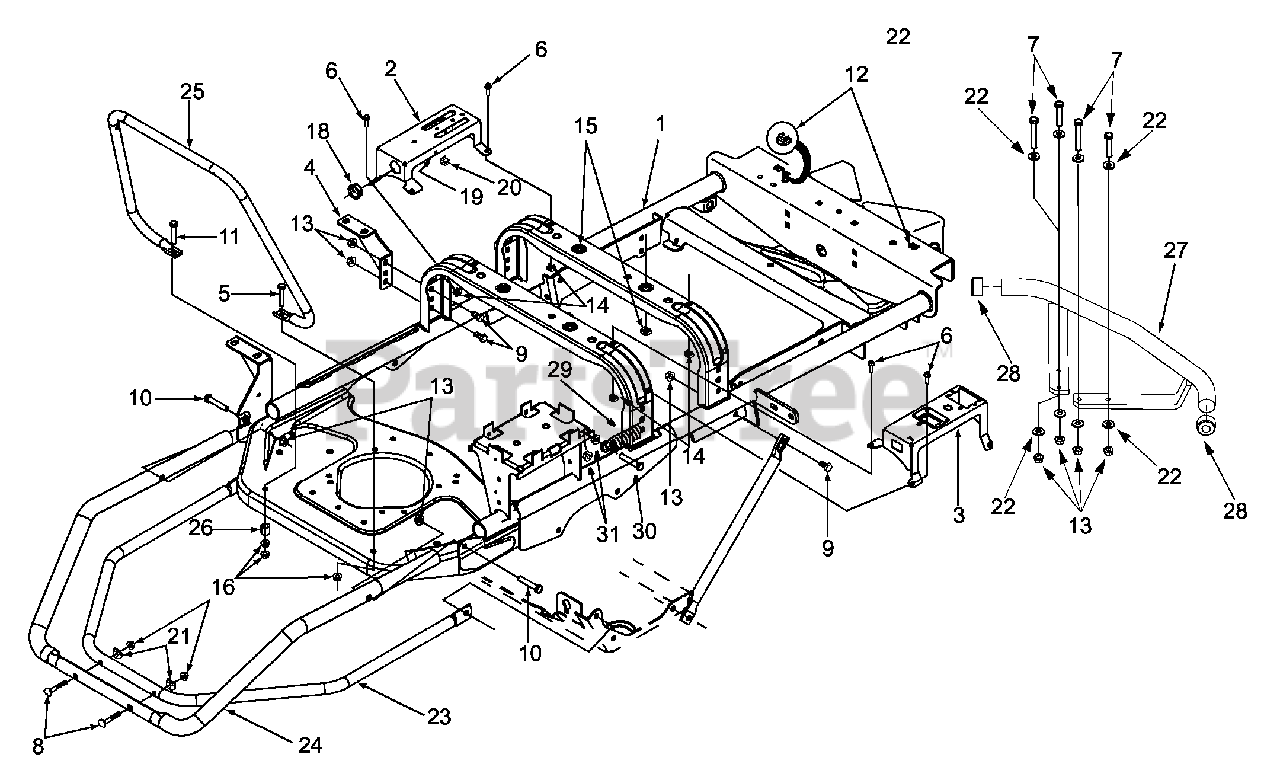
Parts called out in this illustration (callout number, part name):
6	Hex Washer Screw 1/4-20 x .625
7	Hex Cap Screw 3/8-16 x 1.5
8	Curved Carriage Screw 5/16-18 x 2.0
9	Hex Cap Screw 3/8-16 x 3/4
10	Hex Cap Screw 3/8-16 x 2.5
11	Hex Cap Screw 5/16-18 x 1.75
12	Retainer Nut 3/8-16
13	Hex Flange Lock Nut 3/8-16
14	Retainer Nut 1/4-20
15	Retainer Nut 3/8-16
16	Hex Flange Lock Nut 5/16-18
18	Snap Bushing
20	Spring Clip
21	Saddle Washer
22	Flat Washer .406 ID x .875 OD
